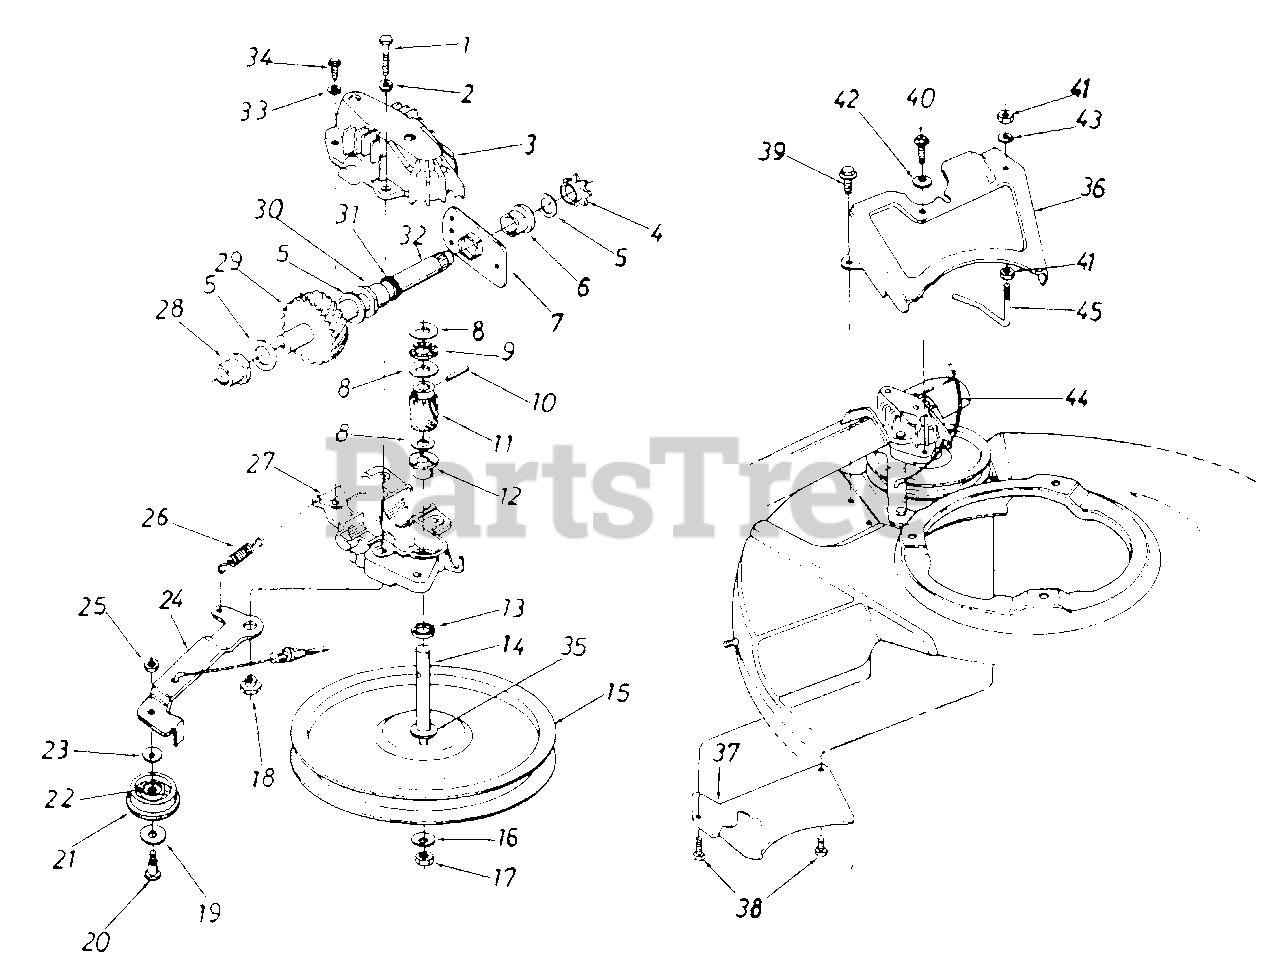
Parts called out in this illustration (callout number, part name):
1	SCREW-HEX 1/4-20 X 1.25
2	LOCK WASHER 1/4 DIA
3	HOUSING HALF-UPPER
4	SPROCKET-7T
5	WASHER-FL
6	BEARING-HEX FLANGE
7	BEARING-CUP HEX
8	WASHER-THRUST.382 X .684
9	BEARING-THRUST
10	PIN-SPRING-SPIR 1/8 X .625
11	GEAR-WORM
12	BEARING-FLANGE
13	SEAL-OIL-.375 ID
14	KIT-TRAN PUL SHFT
15	PULLEY
16	WASHER-SPRING BELL
17	NUT-LH THD-1/4 X 28
18	SPACER-SHLD
19	WASHER-FL .995 X .032
20	SCREW-SHLD
21	KIT-PULLEY
22	BEARING-NEEDLE
23	WASHER-SPRING BELL
24	BRACKET ASSY-IDLER
25	NUT-HEX 1/4-28
26	SPRING-EXTENSION
27	HOUSING HALF-LOWER
28	BEARING-FLANGE
29	SHAFT-ASSY W/GEAR
30	BEARING-FLANGE
32	SHAFT-ASSY W/GEAR
33	WASHER-LOCK-#10
34	SCREW-HEX WASH HD TAP
35	WASHER-HEX
36	GUARD-BELT
37	COVER-BELT
38	SCREW-HEX B-TAP 1/4 X .38
39	SCREW-HEX WASH SF TAPP
40	SCREW-HEX B-TAP 1/4-.62
41	NUT-HEX 1/4-20
42	WASHER-SPRING BELL
43	LOCK WASHER 1/4 DIA
44	CABLE-CLUTCH X 50.0
45	GUARD-BELT
